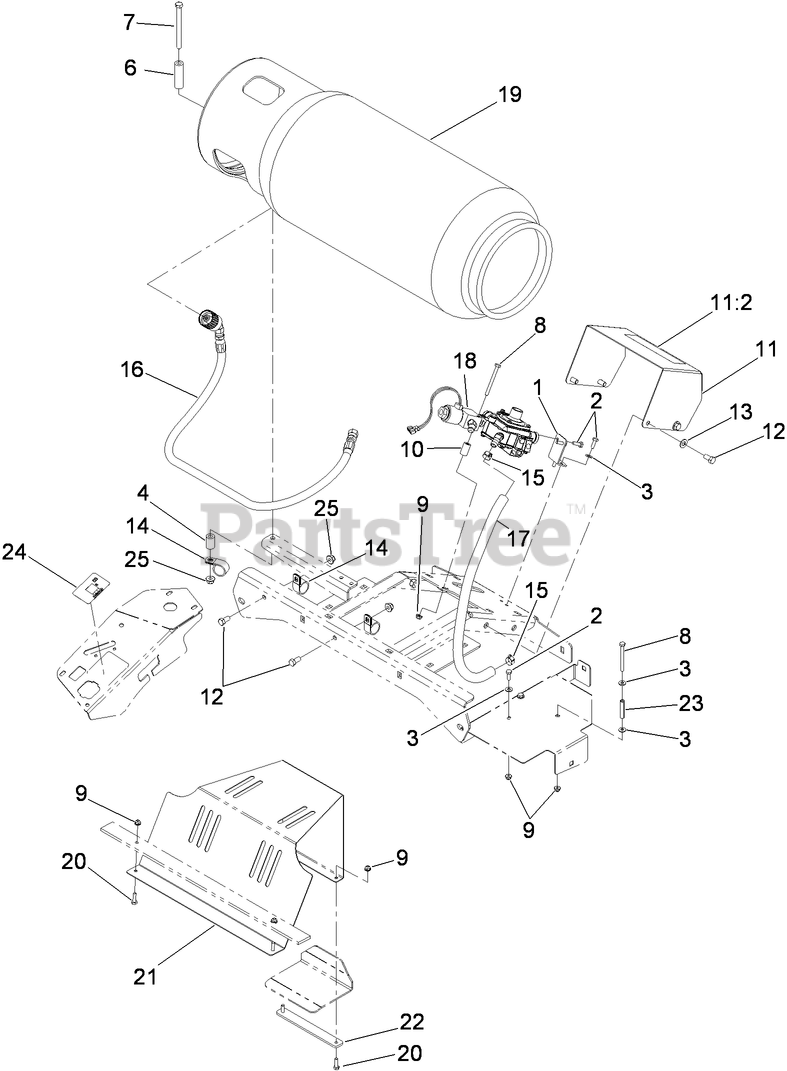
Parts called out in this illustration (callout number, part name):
1	BRACKET-REGULATOR
2	SCREW-HH
3	WASHER-FLAT
4	SPACER-HYDRO CONTROL, LH
6	SPACER-ANCHOR, CLUTCH
7	SCREW-HH
8	SCREW-HH
9	NUT-HF
10	SPACER
11	COVER ASM
11:2	DECAL-TANK REPLACEMENT
12	SCREW-HH
13	WASHER-FLAT
14	CLIP-LOOM
15	CLAMP-HOSE
16	LPG FUEL HOSE ASM
17	HOSE-LP
18	LP SOLENOID REGULATOR ASM
19	TANK-LPG
20	SCREW-HH
21	SHEILD-FAN
23	SPACER-SPLIT
24	DECAL-METER, HOUR
25	NUT-HF, NI
